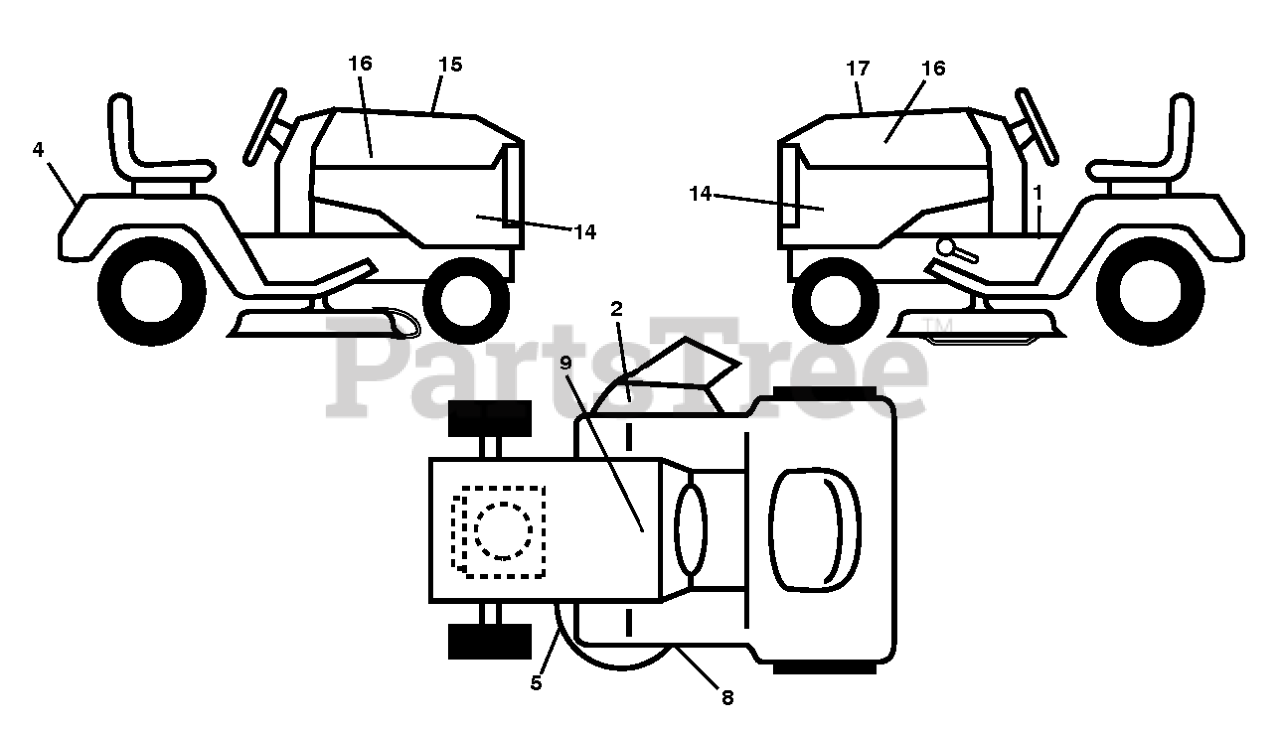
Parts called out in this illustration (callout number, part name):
1	DECAL.WARN.START.INSTRUCTIONS
2	DECAL.WARN.KEEP.HAND.AWAY
4	DECAL.FENDER
5	DECAL.MOWER
8	DECAL.MOWER.SCH.48/54
9	DECAL BTRY SYMBOLS
14	DECAL.SIDE.PANEL.YTH24K48
15	DECAL.WARNING.CUST.RESP.E85.
16	DECAL.BADGE.170MM.TEXTLOGO.
